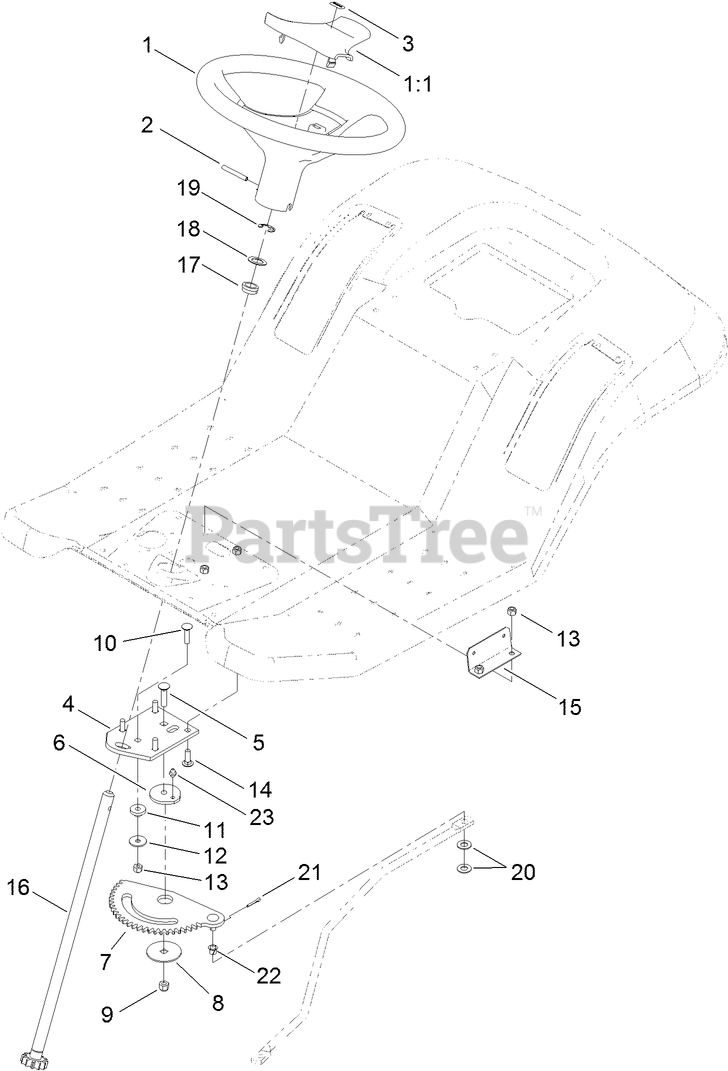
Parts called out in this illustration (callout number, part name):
1	STEERING WHEEL ASM
1:1	COVER-WHEEL, STEERING
2	PIN-ROLL
3	DECAL
4	BRACKET-RACK, STEERING
5	SCREW-CARR
6	BUSHING-ECCENTRIC
7	RACK-STEERING
8	WASHER-BEARING
9	NUT-LOCK, NI
10	SCREW-CARR
11	SPACER-RACK, STEERING
12	WASHER-PIVOT
13	NUT-LOCK, NI
14	BOLT-CARR
15	BRACKET-MODULE
16	SHAFT-STEERING, LONG
17	BEARING-FLANGE
18	WASHER-THRUST
19	E-RING
20	WASHER-FLAT
21	PIN-COTTER
22	BUSHING-FLANGED, NYLON
23	FITTING-GREASE
